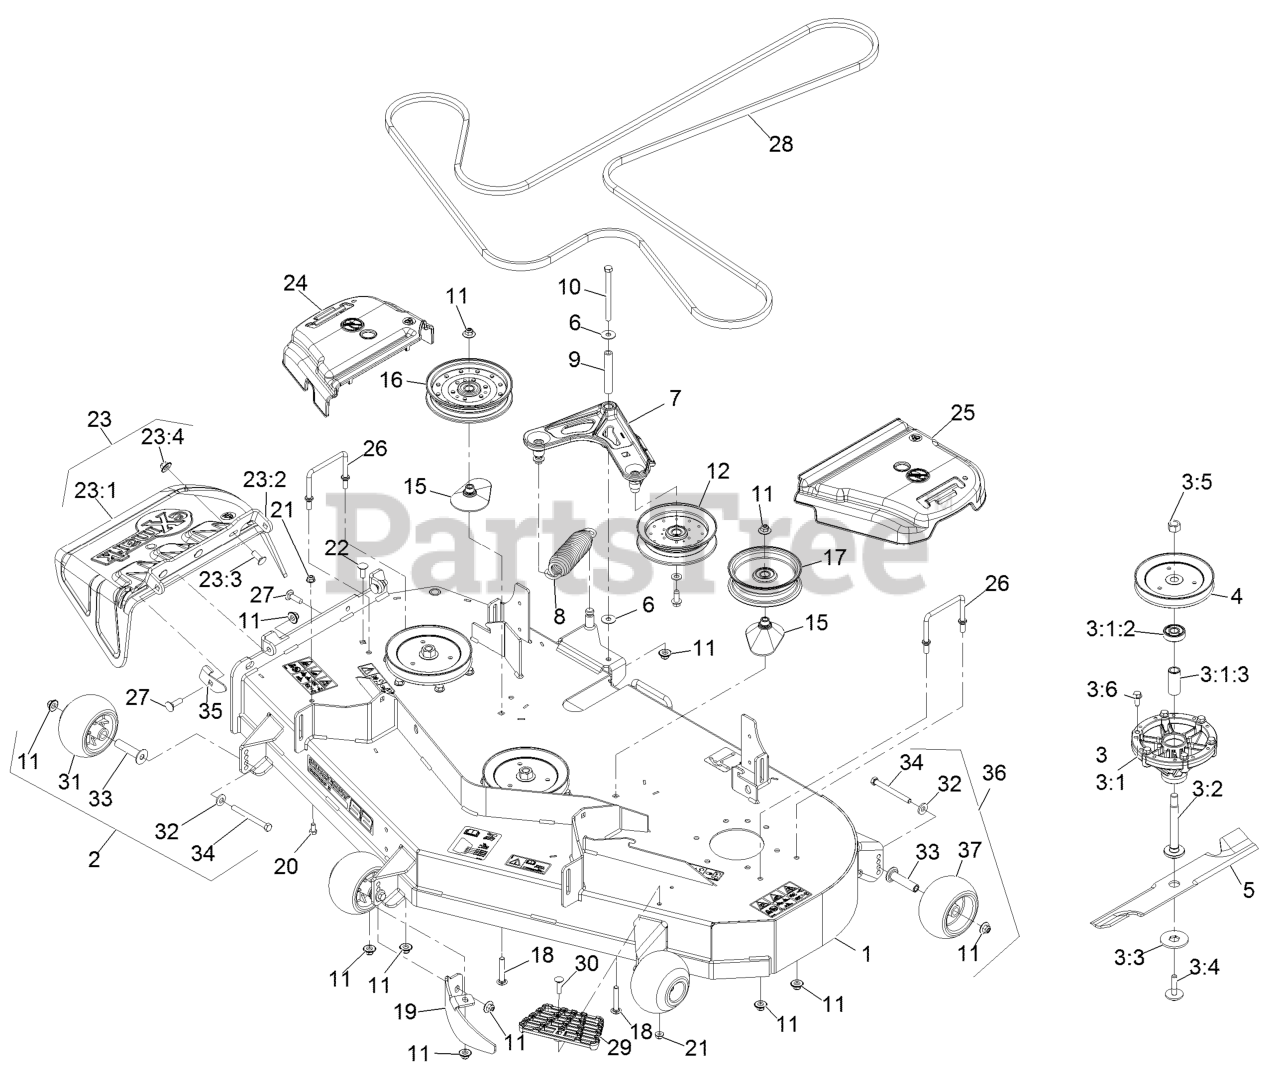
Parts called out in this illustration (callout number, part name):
1	ASM-DECK W/DECALS 523
2	KIT, ANTI-SCALP ROLLER
3	ASM, CUTTER HOUSING COMPL
3:1	ASM-CUTTER HOUSING
3:1:2	BEARING
3:1:3	SPACER-BEARING
3:2	SPINDLE-HEX PILOT
3:3	WASHER-HEX BLADE DRIVE
3:4	BOLT-BLADE, SEM
3:5	NUT-HEX
3:6	SCREW-FORMING, THREAD
4	SHEAVE,BLADE DRIVE 6.50
7	IDLER ARM ASM
8	SPRING-EXTENSION
9	BUSHING
10	SCREW-HH
11	Nut-Nyloc 3/8-16 Flg
15	SPACER-PULLEY
17	IDLER-PULLEY, FLAT
18	BOLT-CARR, SHORT NECK
19	BAFFLE-DOGLEG, LZE-PNS-52
20	SCREW-HH
21	NUT-HF, NI
22	SCREW-CARR
23	ASM,DISCHARGE CHUTE
23:1	CHUTE,DISCHARGE
23:2	BRACKET,DISCHARGE CHUTE
23:3	SCREW-CARR
23:4	Nut-Nyloc 3/8-16 Flg
24	COVER-BELT, RH
25	COVER-BELT, LH
26	WIREFORM-COVER
27	BOLT-CARR
28	BELT-V
29	STEP-DECK
30	Bolt-Carriage 5/16-18 X 1 1/4
31	ROLLER-SCALP, ANTI
32	WASHER-BELLEVILLE
33	AXLE, ROLLER
34	SCREW-HH 3/8-16 X 3 3/4 GR 8
35	STOP-DISCHARGE CHUTE
36	KIT-ANTISCALP ROLLER
37	ROLLER-SCALP, ANTI
